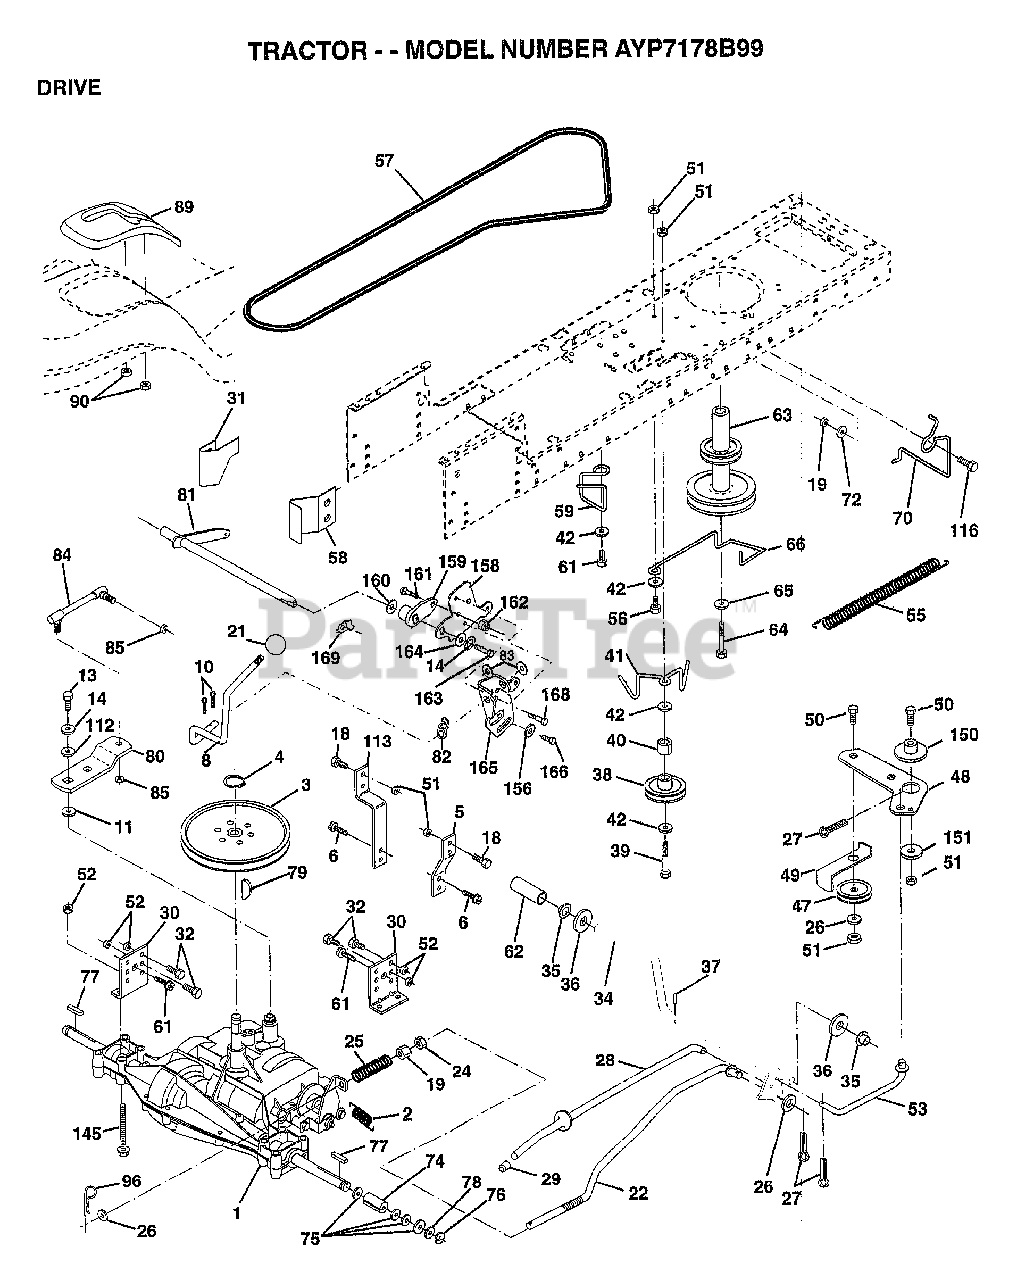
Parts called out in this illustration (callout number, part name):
2	SPRING.BRAKE.RETU
3	PULLEY TRANS
5	STRAP TORQUE
6	SCREW
8	RODL.SHIFT.FEND.ADJ.STLT
10	PIN COTTER 1/8
11	WASH-SHFT PLT LT
13	BOLT.1/4-28.W/PAT
14	LOCKWASHER
18	BOLT
19	NUT
21	KNOB T (1/2-HOLE)
22	BRAKE ROD
24	NUT
25	SPRING ROD LT
26	WASHER
27	COTTER PIN
28	ROD.BRAKE.PARK.LT
30	TRANSAXLE MTG BKT
31	"KEEPER,BELT LH T"
32	BOLT
34	SHAFT ASM-PEDAL F
35	NYLON BEARING
36	WASHER LT
38	FLAT IDLER PULLEY
39	BOLT
40	SPACER T
41	"KEEPER,BELT.IDLER FLAT"
42	WASHER
48	BELLCRANK.CLUTCH
49	RETAIN BELT
53	"LINK, CLUTCH T"
55	"SPRING, RETURN LT"
58	"KEEPER,BELT RH T"
59	KEEPER BELT CNTSP
61	SCREW
62	PEDAL COVER T
63	PULLEY.ENGINE
64	BOLT
65	LOCKWASHER
66	KEEPER-BELT
70	KEEPER BELT ENG
72	WASHER
74	SPACER AXLE
75	WASHER
76	E-RING LT
77	SQUARE KEY
78	WASHER
80	"ARM.SHIFT.20""TIRE"
81	SHAFT.ASM.CROSS
82	SPRING.SHIFT.STLT.GREY
83	WASHER
84	LINK.TRANSAXLE.PMST/DANA
85	NUT.CNT.LOCK.1/4
89	CONSOLE.SHIFT.STLT.6SP.BLACK
90	NUT
96	RETAINER M
112	WASHER LT
113	"STRAP,TORQUE"
116	BOLT RDHD 3/8-16
145	BOLT.HEX.FLGHD
150	BUSHING.BELLCRANK.GRD.DR
151	WASHER
156	WASHER.SRRTD.5/16
158	BRKT.SHIFT.MOUNT
159	HUB.SHIFT
160	WASHER
161	BOLT T
164	WASHER.5/8X.281X10GA
165	BRKT.PIVOT.LEVER
166	SCREW.5/16-18X5/8
168	BOLT.SHOULDER.5/16-18X.561
169	PLATE.FASTENING
